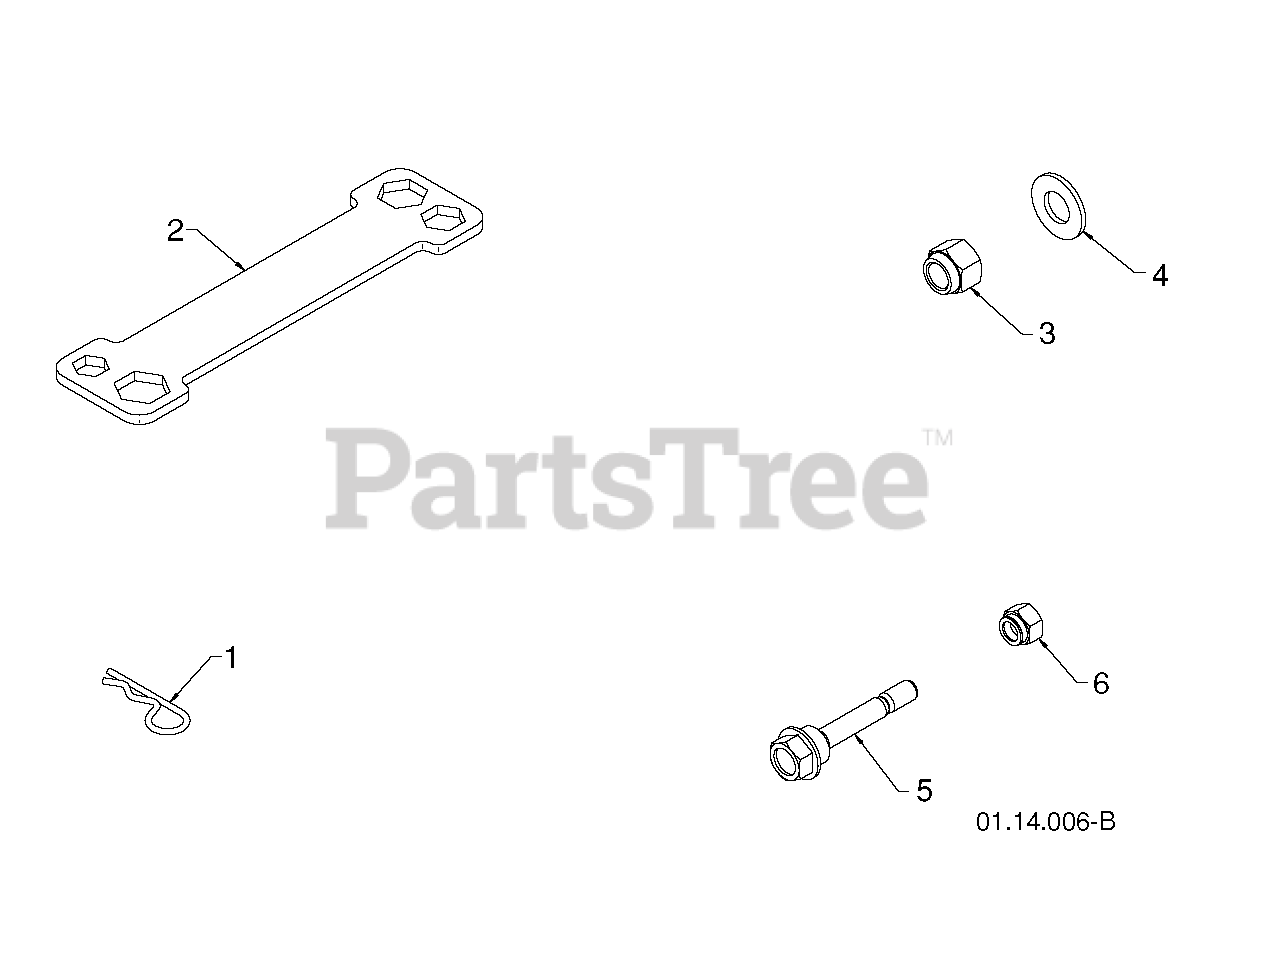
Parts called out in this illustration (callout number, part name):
1	SPRING RETAINER
2	WRENCH.SNOWTHROWER
3	NUT
5	BOLT, SHOULDER SHEAR
6	LOCKNUT
